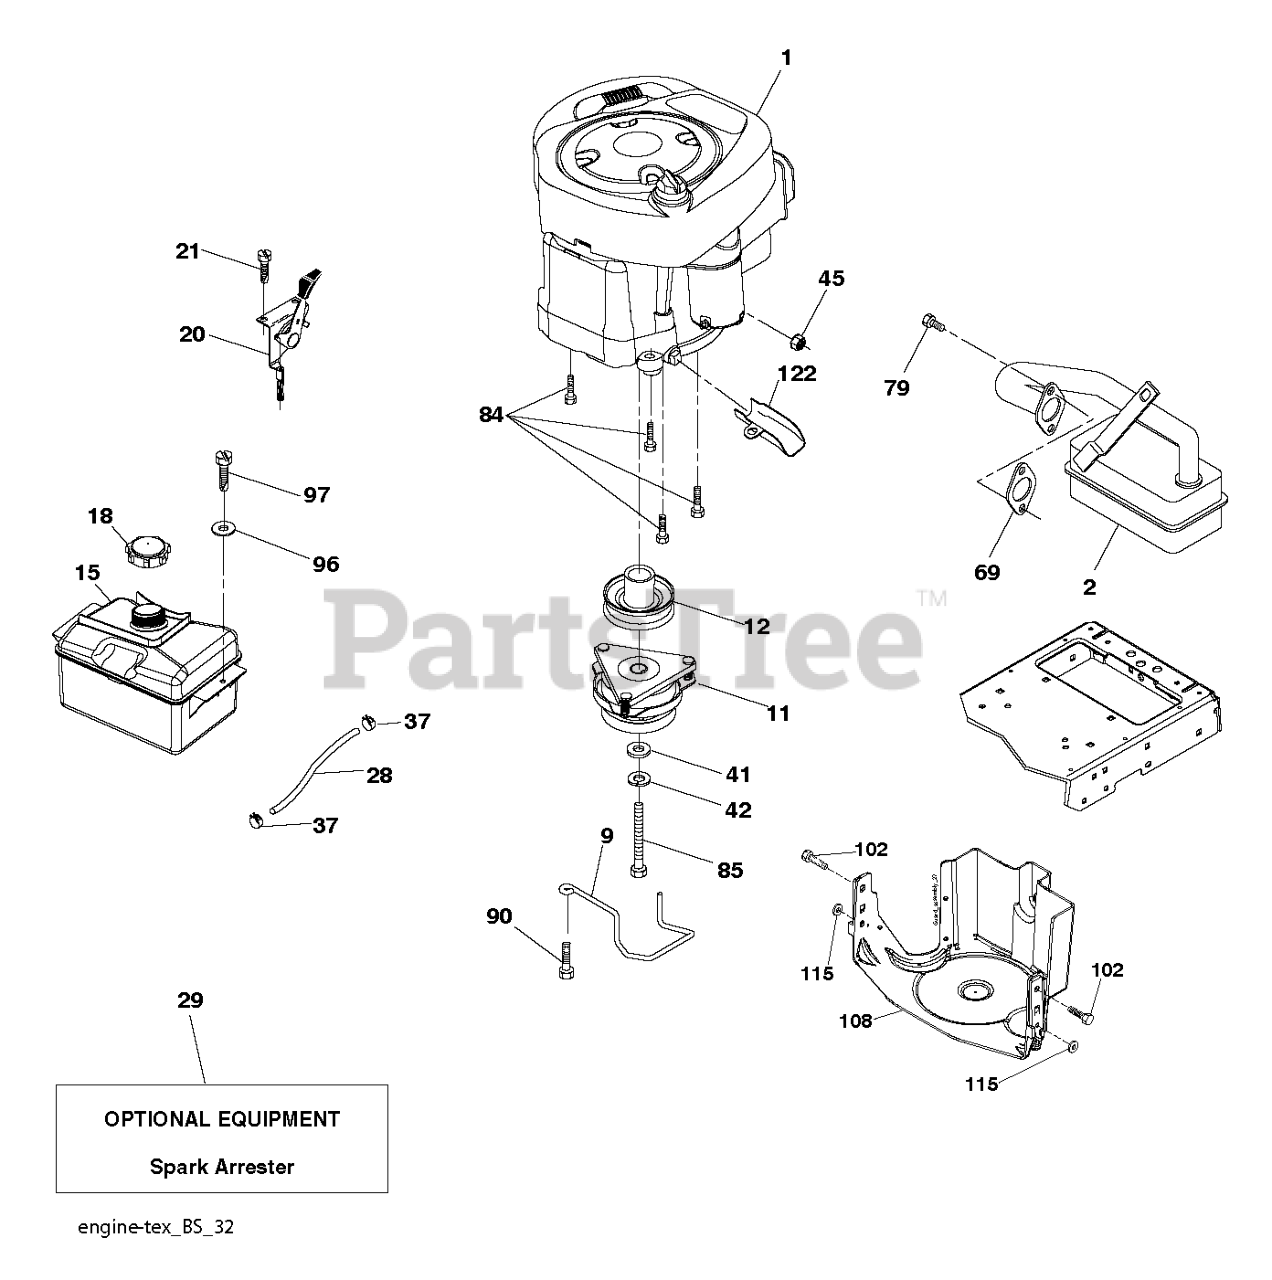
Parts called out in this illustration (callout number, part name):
2	MUFFLER.B&S.MODEL.21.11HP.OHV
9	KEEPER.BELT.ENGINE.3.25 (3 2)
11	RB.CLUTCH.OGURA.4.4.PD
12	PULLEY.ASM.ENG.OGURA.3
15	RP TANK FUEL FRT 1.5 GAL
18	CAP ASM.FUEL.2.25"FR.
20	CONTROL.TH/CK.C.
21	SCREW.#10 X 0.750.BOS
28	LINE.FUEL.20
29	KIT.SPARK ARRESTOR 794945 B&S
37	HOSE CLAMP
42	LOCKWASHER
45	NUT
69	REPL BY 532 27 22-93
79	SCREW.SOCKET HD.5/16-1
84	SCREW.3/8-16
85	BOLT HEX 7/16-20X4-1/4"
90	SCREW 3/8-16X1
96	WASHER
97	SCREW HEXWSHR 1/4-20X3/4
102	SCREW
108	COVER PULLEY
115	PALNUT 1/4
122	EXTENSION DRAIN OIL
